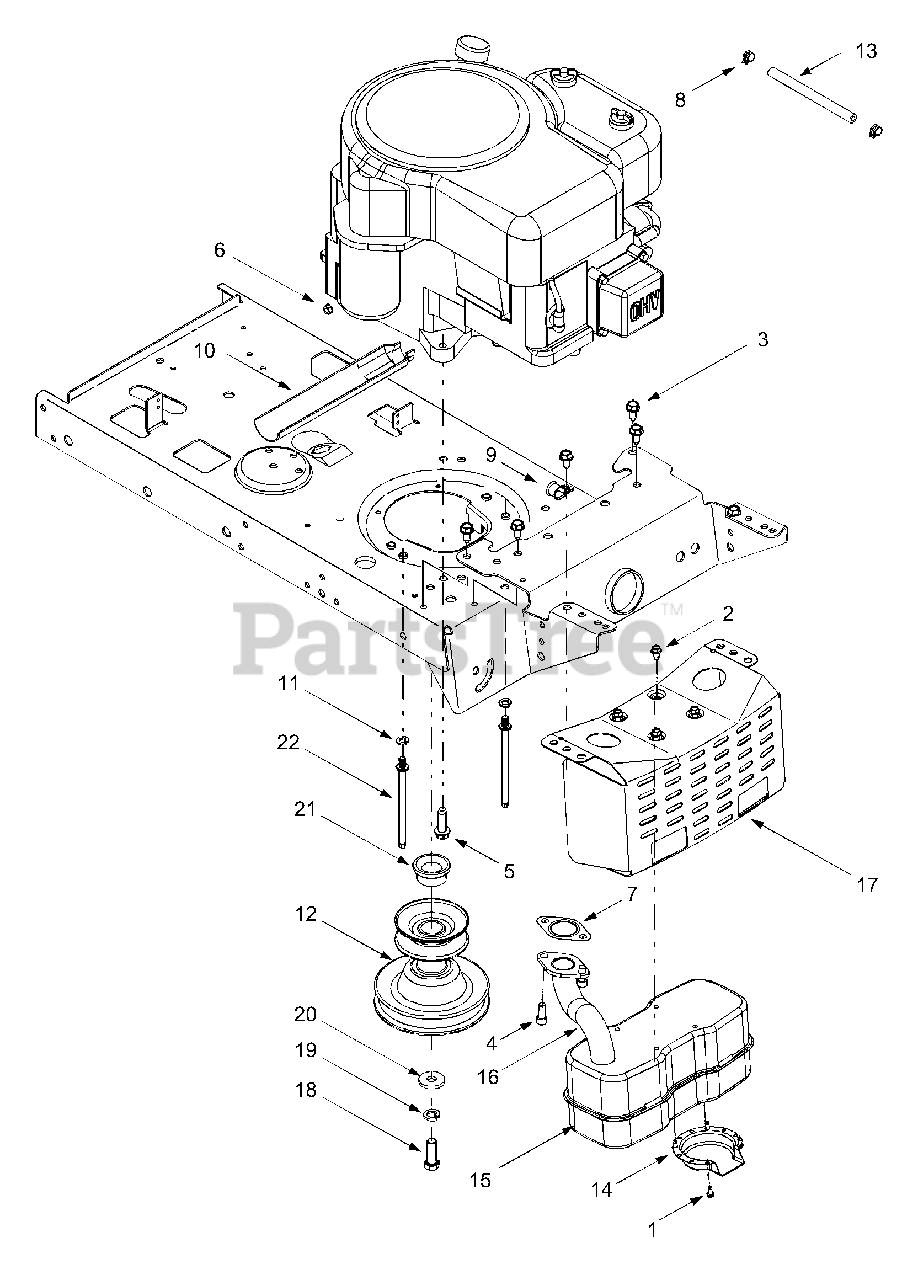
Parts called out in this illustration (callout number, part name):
1	Screw, #8-32 x .375
2	Self-tapping Screw, 1/4-20 x .5
3	Self-tapping Screw, 5/16-12 x .75
4	Socket Cap Screw, 5/16-18 x .
5	Self-tapping Screw, 3/8-16 x 1.25
6	Hex Sems Nut, 1/4-20
7	Exhaust Gasket
8	Hose Clamp, .490
10	Oil Drain Sleeve
11	Lock Washer, 5/16
12	Engine Pulley, 3.39 X 5.56
13	Fuel Line Hose
14	Muffler Deflector
15	Muffer, Single Inlet
16	Exhaust Pipe
18	Hex Screw, 7/16-20 x 1.25
19	Lock Washer, 7/16
20	Flat Washer, .450 x 1.25 x .164
21	Spacer, 1.0 x 1.4 x .825
22	Belt Keeper Pin, 5/16 x 4.75
